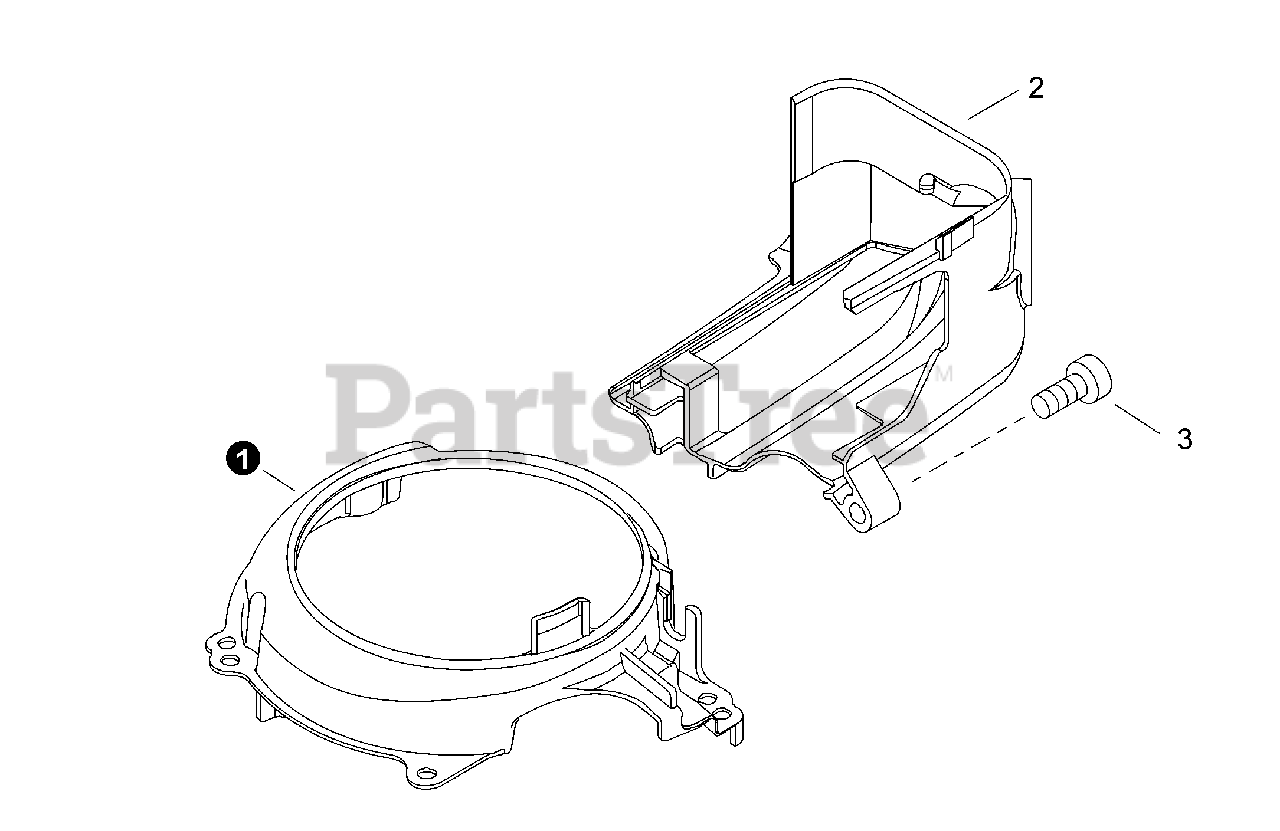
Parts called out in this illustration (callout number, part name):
1	COVER, FAN
2	COVER, ENGINE
3	BOLT, TORX 5×16
